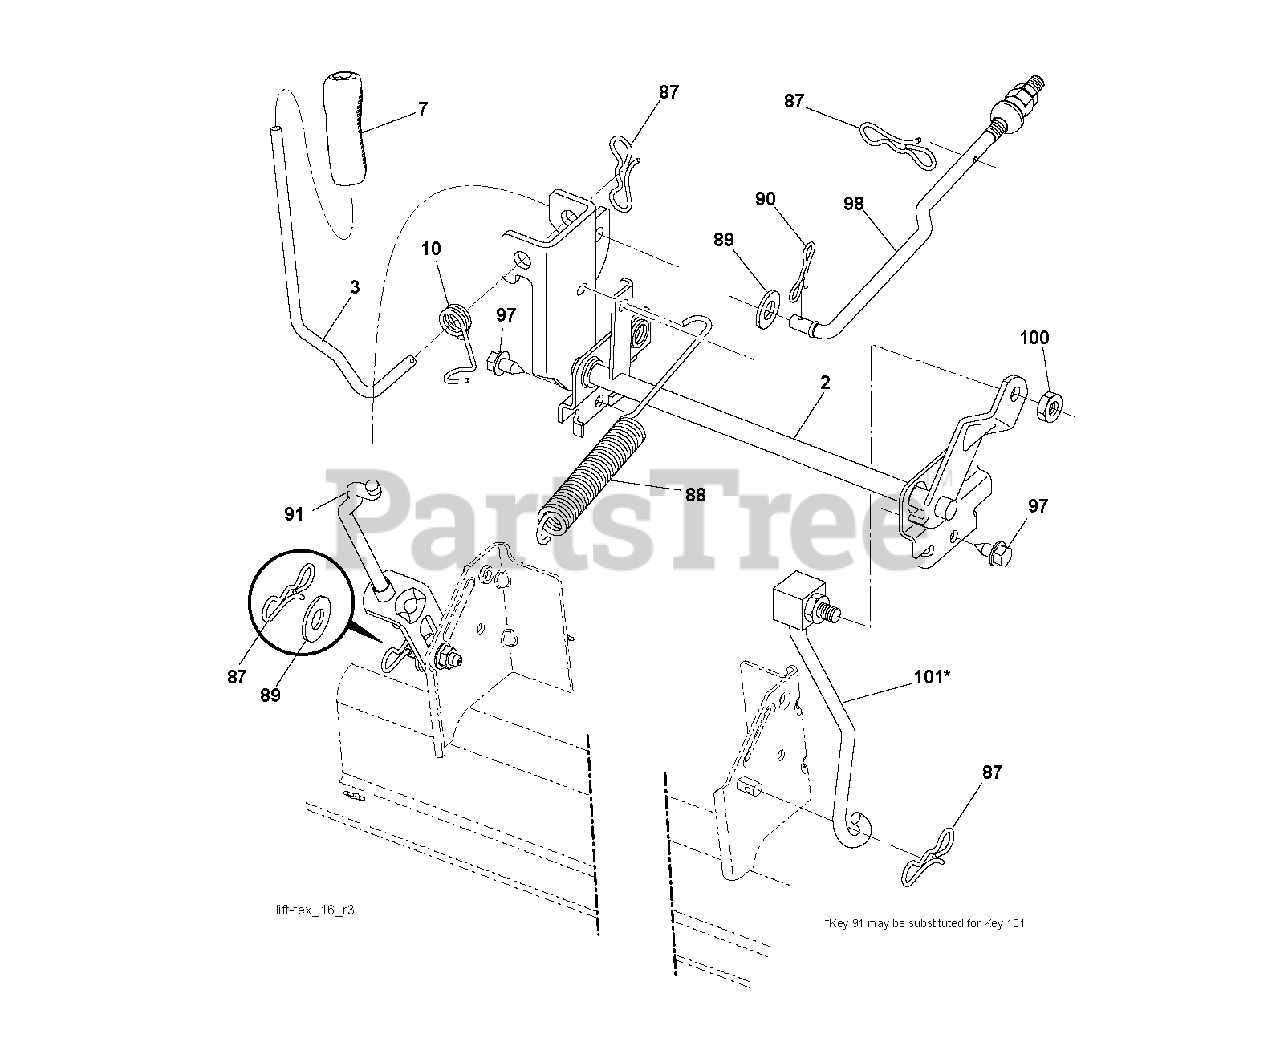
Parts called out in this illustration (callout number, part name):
2	SHAFT.ASM.CROSS.LIFT
3	LEVER.LIFT.HANDLE.LT
7	GRIP.HANDLE.LIFT.PVC.BLACK
10	SPRING.TORSION.LIFT.HANDLE
87	PIN.COTTER.7/16.BOW TI
88	SPRING.LIFT.ASSIST
89	WASHER.CLEAR.ZINC
90	PIN.COTTER.5/16.BOW TI
91	LINK.ASM.LIFT.REAR
97	SCREW, 3/8-16X3/4
98	LINK.ASM.SUSP.FRONT.MW
100	LOCKNUT
101	LINK.ASM.LIFT.FIXE.38/42/46"
